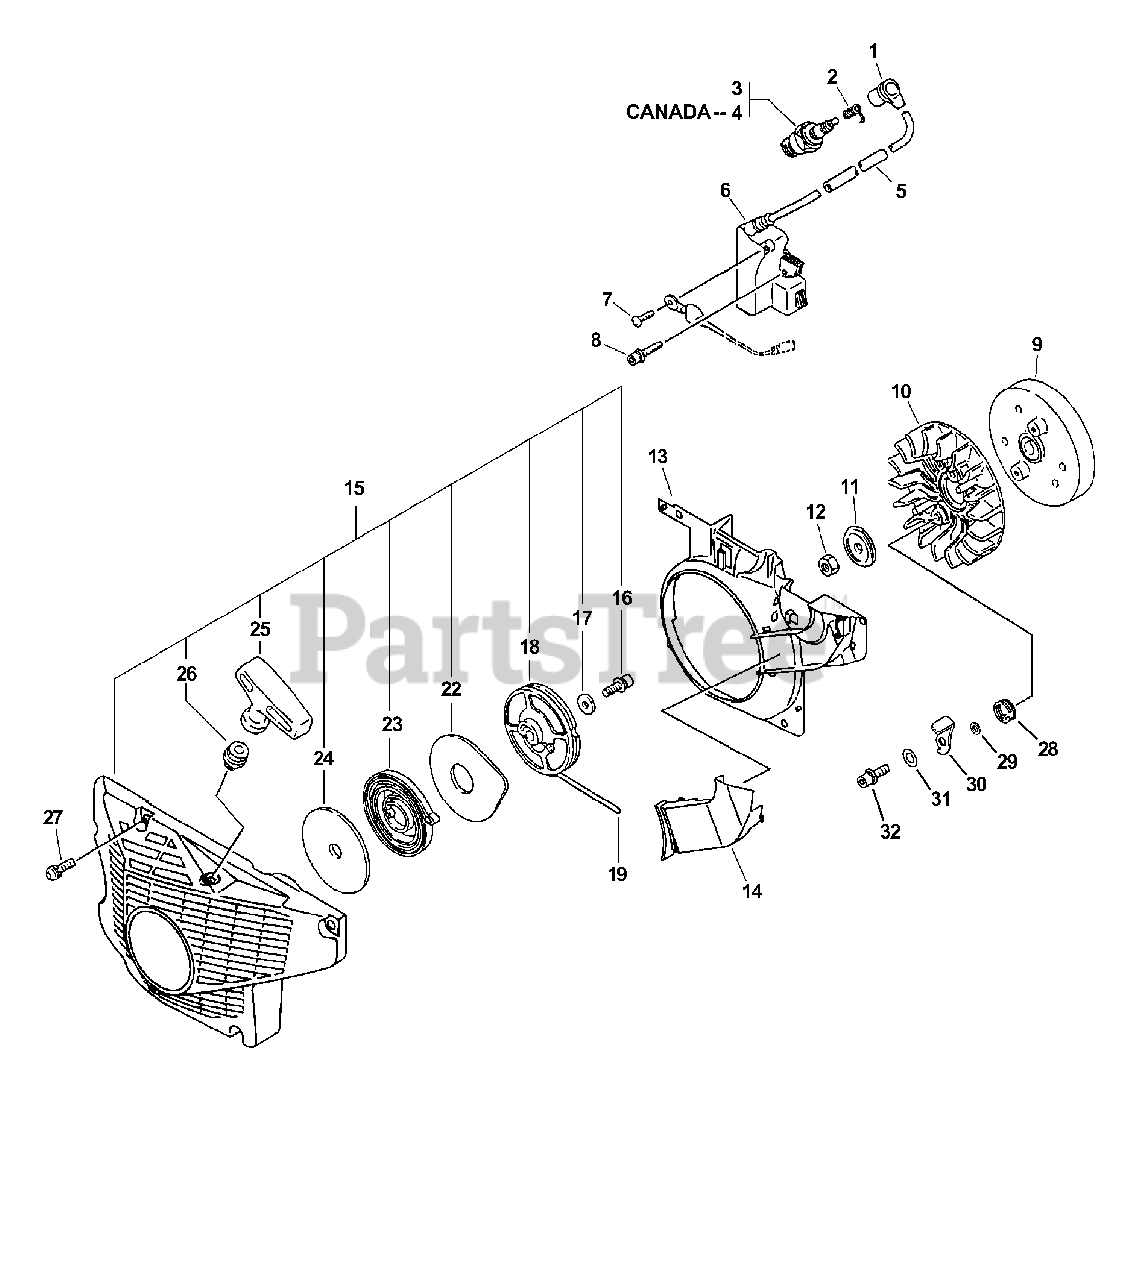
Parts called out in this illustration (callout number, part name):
1	CAP, SPARK PLUG
2	TERMINAL, SPARK PLUG
3	SPARK PLUG - BPM7A
4	SPARK PLUG - BPMR7A
6	COIL, IGNITION
7	SCREW 4×8
8	BOLT 4×20
9	FLYWHEEL
11	WASHER 8.2×31×0.8
13	COVER, FAN
14	DUCT, AIR
15	STARTER ASSY
16	BOLT 5×14
17	WASHER 5.5×12×0.8
18	REEL, ROPE
19	ROPE, STARTER 4.0×950
20	SCREW 4×8
21	PLATE, EYE
22	PLATE, STARTER
23	SPRING, RECOIL
24	PLATE, STARTER
25	GRIP, STARTER
26	GUIDE, ROPE
27	BOLT 5×20
28	SPRING, RETURN
29	COLLAR 5
30	PAWL, STARTER
31	WASHER 5.5×12×0.8
32	BOLT 5×18
